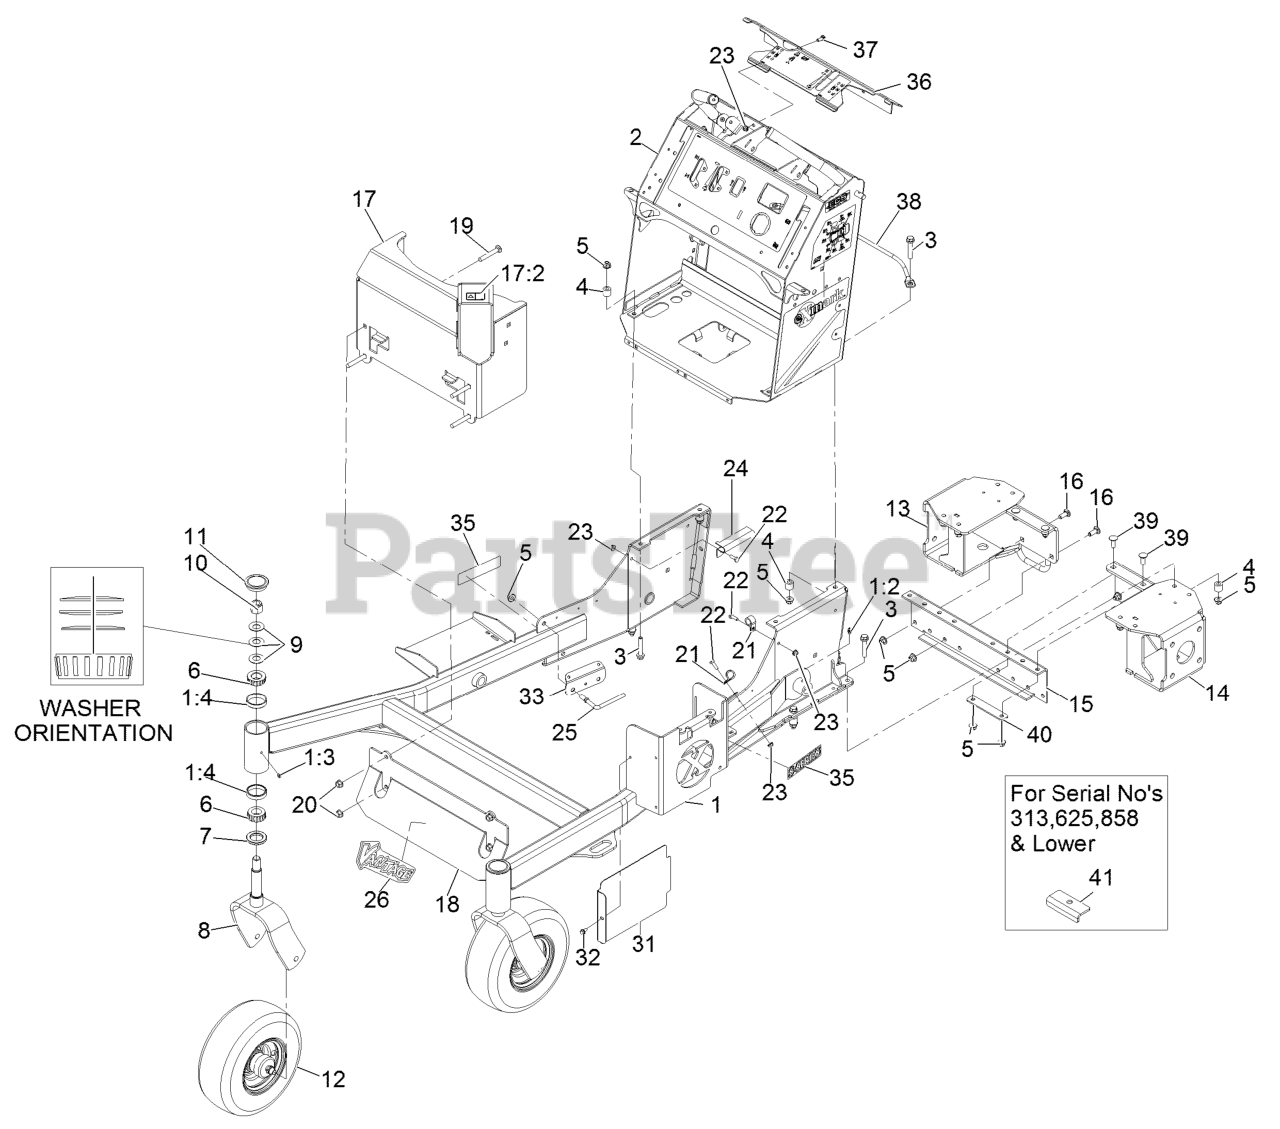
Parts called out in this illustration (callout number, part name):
1	FRONT FRAME ASM
1:2	FITTING-GREASE
1:4	CUP-BEARING
2	TOWER ASSEMBLY
3	SCREW-HHF
5	NUT-HF, NI
6	Cone-Bearing Tapered Roller
7	SEAL-GREASE
8	FORK-CASTER
9	WASHER-BELLVILLE
10	NUT-LOCK, NI
11	CAP-GREASE
12	WHEEL/TIRE AND BEARING AS
13	RH MOTOR MOUNT ASM
14	LH MOTOR MOUNT ASM
15	MOUNT-MOTOR, CENTER
16	SCREW-CARR
17:2	DECAL-WARNING
18	PANEL-GUARD
19	SCREW-CARR
21	CLAMP-CABLE
22	SCREW-HH
24	BRACKET-HOSE, FUEL
25	GUIDE-HOSE, SUPPORT
26	DECAL-VANTAGE LOGO
31	SHIELD-HEAT, TALL
32	SCREW-HWH
33	GUARD-HOSE
35	DECAL-X-SERIES
36	CONTROL PANEL W/DECALS
37	BOLT-CARR
38	ROD, GUARD
39	Bolt-Carriage 3/8-16 X 1 1/4
40	SPACER, UP STOP
41	Spacer-Up Stop
